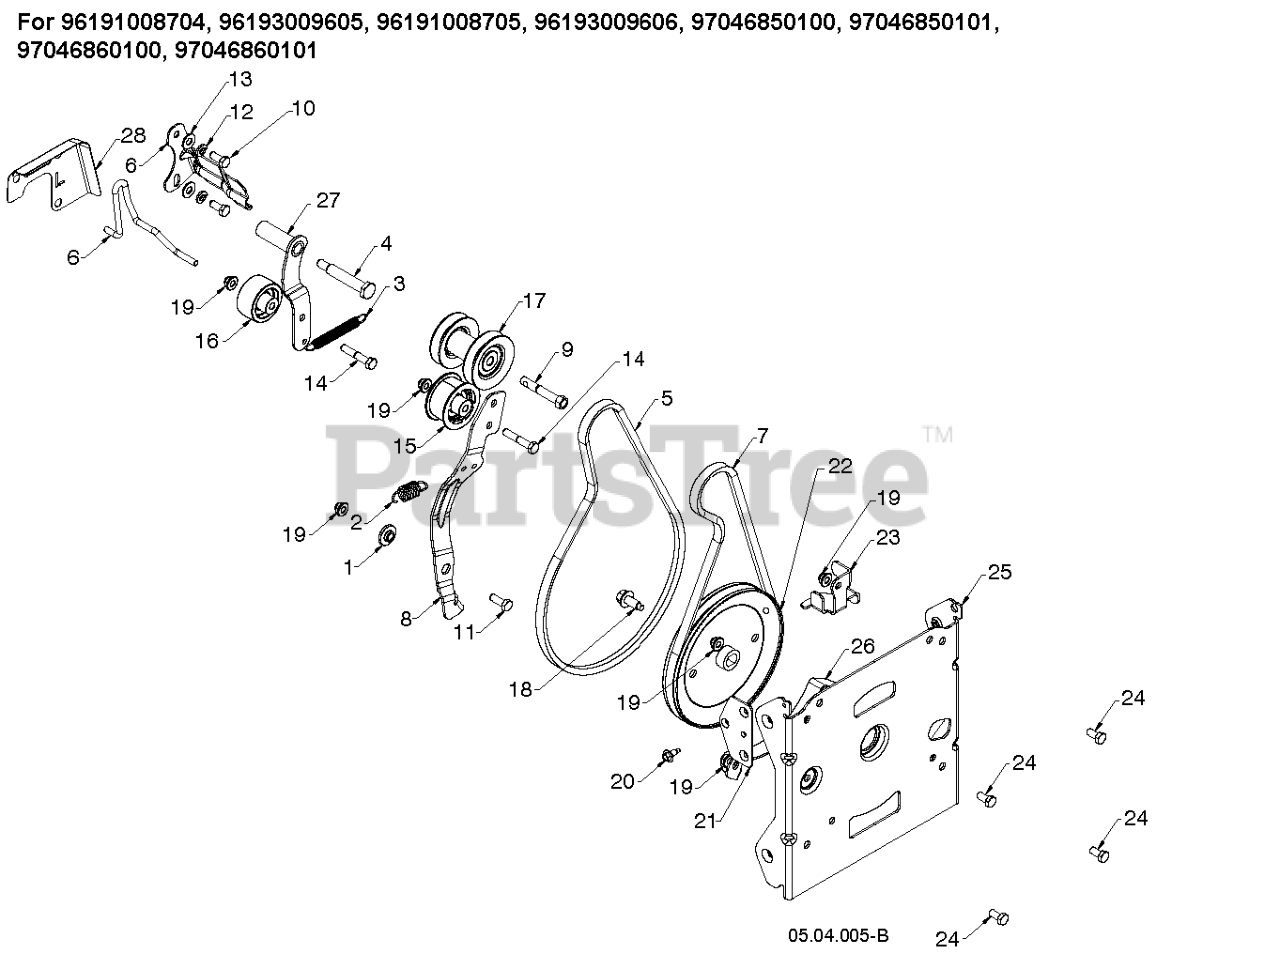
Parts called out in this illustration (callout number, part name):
1	BUSHING.BRAKE.ARM
2	SPRING RETURN, IDLER ARM, IMPE
3	SPRING RETURN IDLER ARM
4	BOLT 5/16-24X2.25 HEX HEAD SHO
5	Belts
5	BELT.DRIVE.SNOW.DUAL
6	BELT KEEPER BRACKET
6	Belt Keepers
7	LOW CRANK IMPELLER BELT
8	ARM.IDLER.AUTO-PH.676
9	BOLTS
9	BOLT.ENGINE.PULLEY
10	SCREW
10	SCREW 5/16-24 X .75 GR5
11	BOLT HEXAGON BOLT 5/16-18 X 7/
11	BOLT
12	WASHER SPRING LOCK WASHER WITH
12	WASHER.LOCK.HVY.HLCL.SPR.5/16
13	WASHER 11/32 X 11/16 X 14 GA T
14	BOLT, HEX 5/16-18X1-3/4
15	PULLEY.IDLER.FLNGLESS.W/SPACER
15	PULLEYIDLER.2.0.W/SPACER.CZ
16	PULLEYIDLER.2.0.W/SPACER.CZ
16	PULLEY 4L GEAR - LC
16	PULLEY.IDLER.FLNGLESS.W/SPACER
17	PULLEY.ASM.IMPELLER/DRIVE
17	Engines
18	SCREW HEXAGON HEAD FLANGE 3/8-
18	SCREW FLANGE HEAD CAP WITH DOG
18	BOLT
19	NUTNYLOK.FLRANGE.5/16-18
19	NUT HEXAGON FLANGE 5/16-18 ST
20	HEX.WASHER.HEAD 1/4-20 X .65
21	BRACKET NUT BLACK ZINC PLATE
22	PULLEYS
22	PULLEY IMPELLER DD 4L
23	GUIDE.LOWER.AUGER.BELT.479
24	Screws
24	BOLT, HEX HEAD 5/16-18
25	BRACKET.AUG.HOUSING.INTER.BLAC
26	ARM DRIVE IDLER CLEAR ZINC PLA
26	BRACKET.BELT.KEEPER.LOWER.BLAC
27	ARM IDLER DRIVE WELDMENT_HOT
27	ARM DRIVE IDLER CLEAR ZINC PLA
28	Cranks
